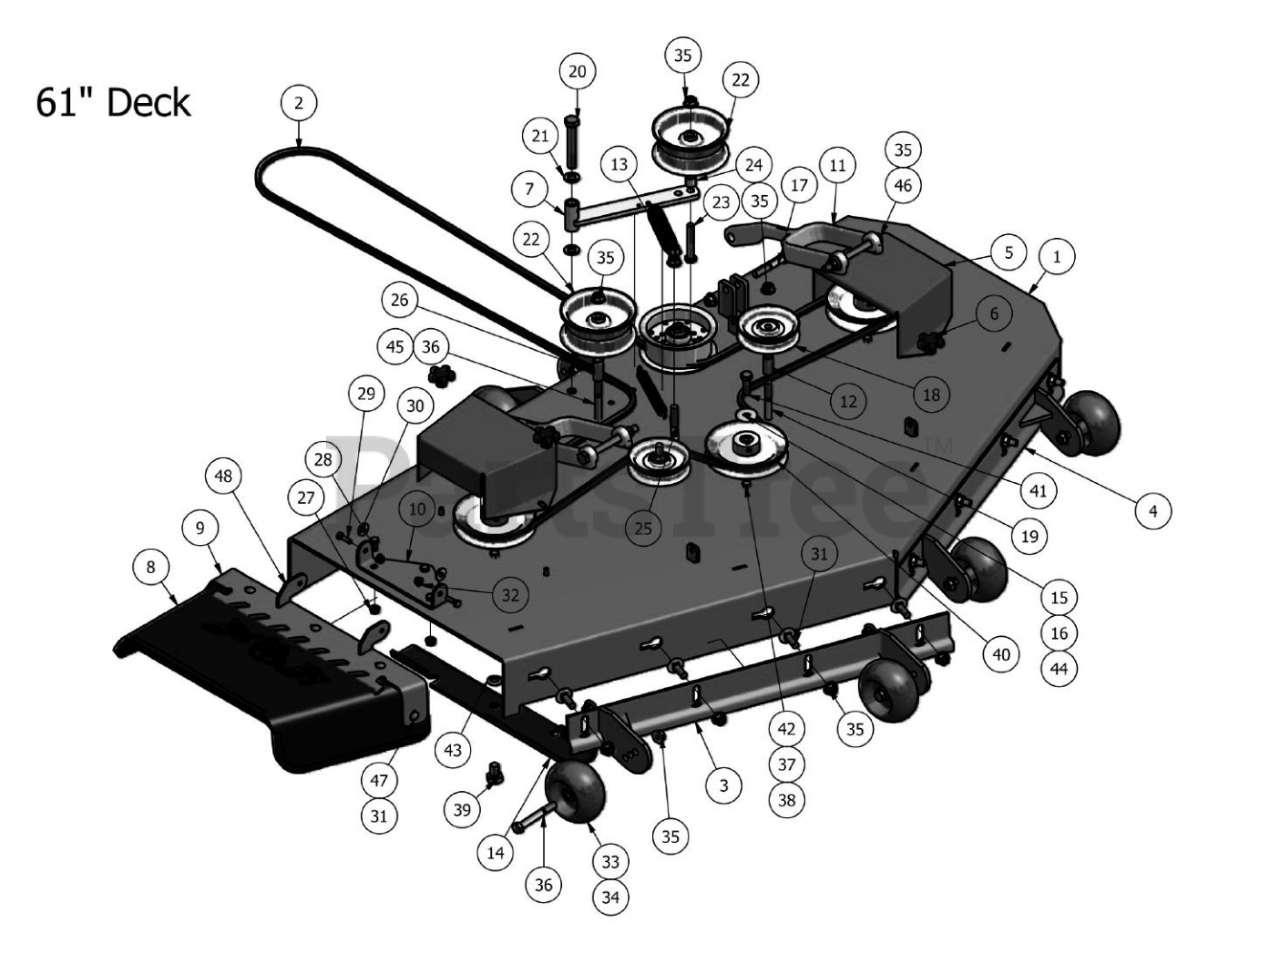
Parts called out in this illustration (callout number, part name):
1	61" Outlaw Deck (Shell Only)
2	61 inch Outlaw Deck Belt
3	61 Outlaw Adjustable Deck Front (Right)
4	61 Outlaw Adjustable Deck Front (Left)
5	Pulley Cover
6	5/16" Knob
7	Deck Idler
8	Rubber Discharge Chute (Rubber Only)
9	60" Discharge Chute Upper Hanger Plate
10	Discharge Chute Hanger (deck mounted)
11	Deck Arm Assembly
12	Pulley Spacer
13	Deck Idler Spring
14	61 inch Fusion Blade
15	Spring Blade Cupped Washer
16	5/16" Set Screw
17	1/2 x 2-1/2 Hex Bolt
18	4 3/4" Idler Pulley
19	1/2 x 3-1/2 Flange Bolt - Grade 8
20	5/8" x 4" Hex Bolt
21	.635 ID Plastic Washer
22	5 3/4" Flat Idler Pulley-32FI-92-008
23	1/2" x 3" Hex Bolt
24	3/4 OD x 1/2 ID x 3\4 Length
25	1/2 x 2" Carriage Bolt
26	1 3/4" Pulley Spacer
27	3/8-16 Hex Flange Nuts Zinc w/Serrations
28	3/8" x 3/4" Hex Bolt
29	5/16-18 x 1 Grade 5 Hex bolt Zinc
30	.360ID Plastic Washer
31	1/2 x 1-1/4 Carriage Bolt
32	5/16-18Nylon Insert flange Nut zinc Orange Insert
33	Anti-Scalp Rollers
34	Complete Roller Assembly
35	1/2-13 Nylon Insert Flangenut Zinc Orange Nylon
36	1/2" x 4" Bolt (Grade 8)
37	3/8" Hex Nut
38	3/8" Lock Washer
39	5/8-18 X 1-1/2 GR 8 Hex Bolts Zinc Yellow
40	6 1/4" Drive Pulley
41	1/2" x 1 1/2" Hex Bolt
42	3/8-16 x 1-1/4 GR 5 Hex Bolt Zinc
43	5/8 Lock Washer Zinc
44	1/4 X 1 Square Key
45	1/2" Washer (Grade 8)
46	1/2" x 5 1/2" Bolt
47	5/16" x 1 1/4" Carriage Bolt
48	Chute Assembly
